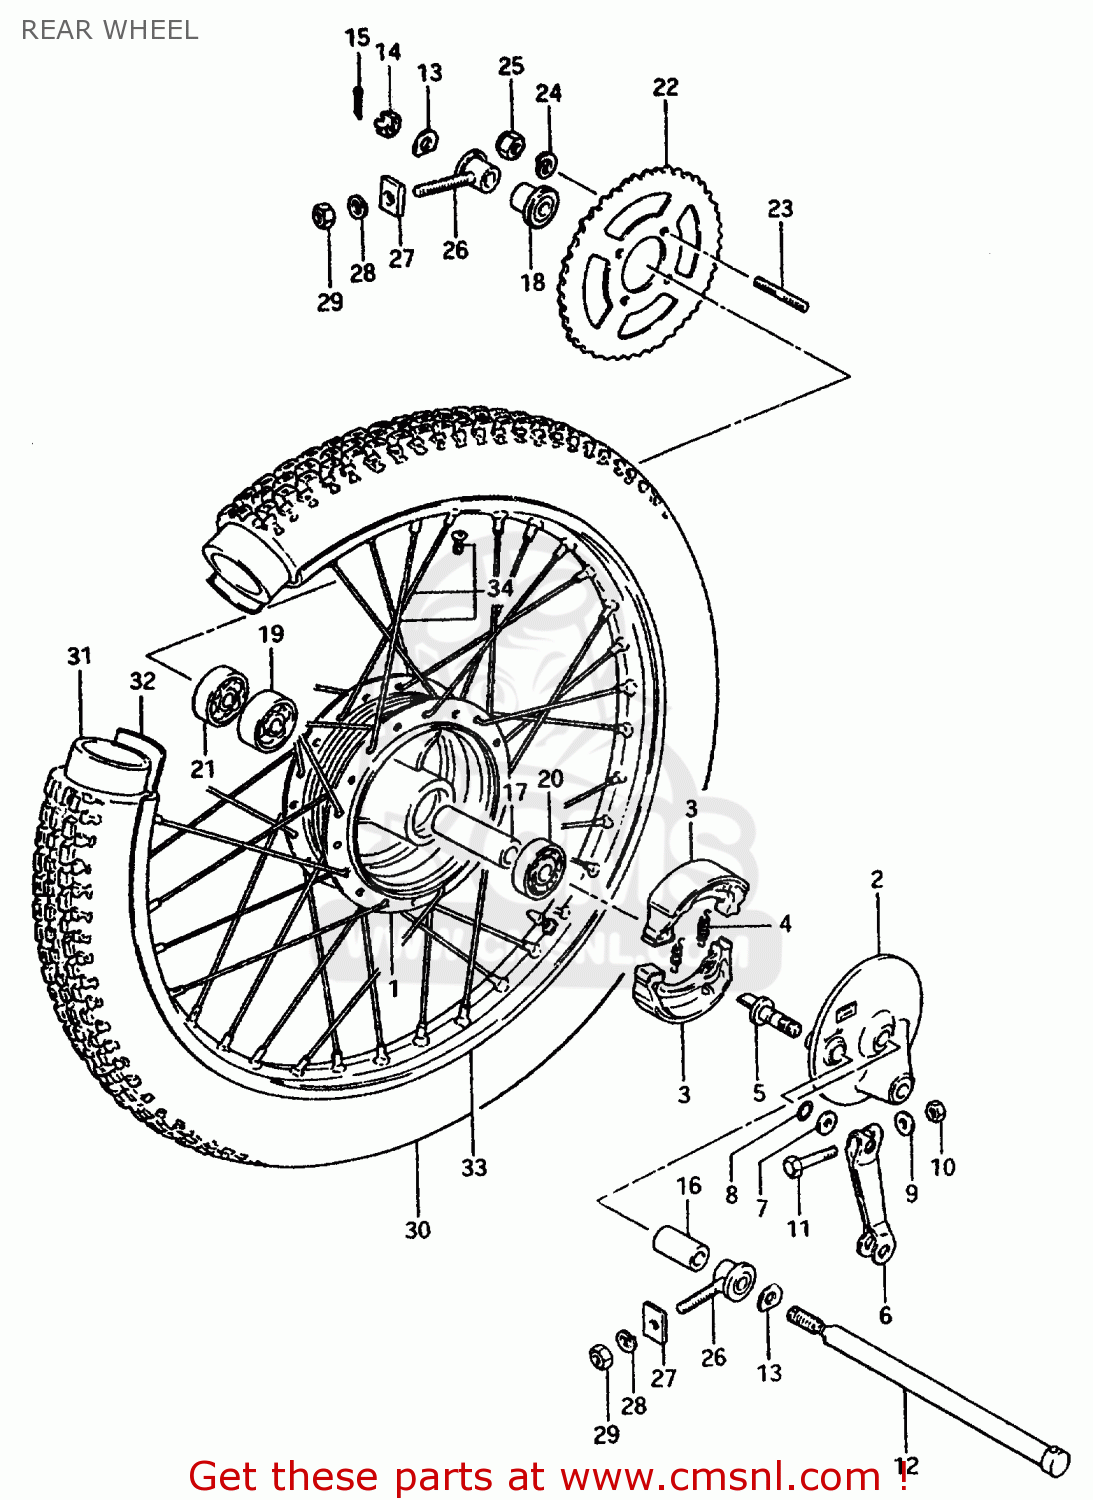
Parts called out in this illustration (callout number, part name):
1	DRUM SET,REAR HUB
2	PANEL,REAR BRAKE ANCHOR
3	SHOE,BRAKE (MCA)
4	SPRING(L:34)
5	CAM,FRONT BRAKE
6	LEVER,RR BRAKE CAM
7	WASHER (14.5X22X1.6)
8	O-RING (D:2.4 ID:13.8)
9	WASHER
10	NUT
11	BOLT(6X33)
12	AXLE,RR
13	WASHER,RR AXLE
14	NUT 12MM
15	COTTER PIN
16	SPACER, AXLE RH
17	SPACER (12.6X19X79)
18	SPACER, REAR AXLE LH
19	BEARING
20	BEARING
21	BEARING
22	SPROCKET, REAR (NT:47)
23	BOLT
24	LOCK WASHER
25	NUT
26	ADJUSTER, CHAIN
27	ADJUSTER,CHAIN
28	LOCK WASHER
29	NUT
30	TIRE (3.00-17)
31	TUBE,INNER
32	PROTECTOR,INNER TUBE
33	RIM, WHEEL
34	SPOKE SET,RR
